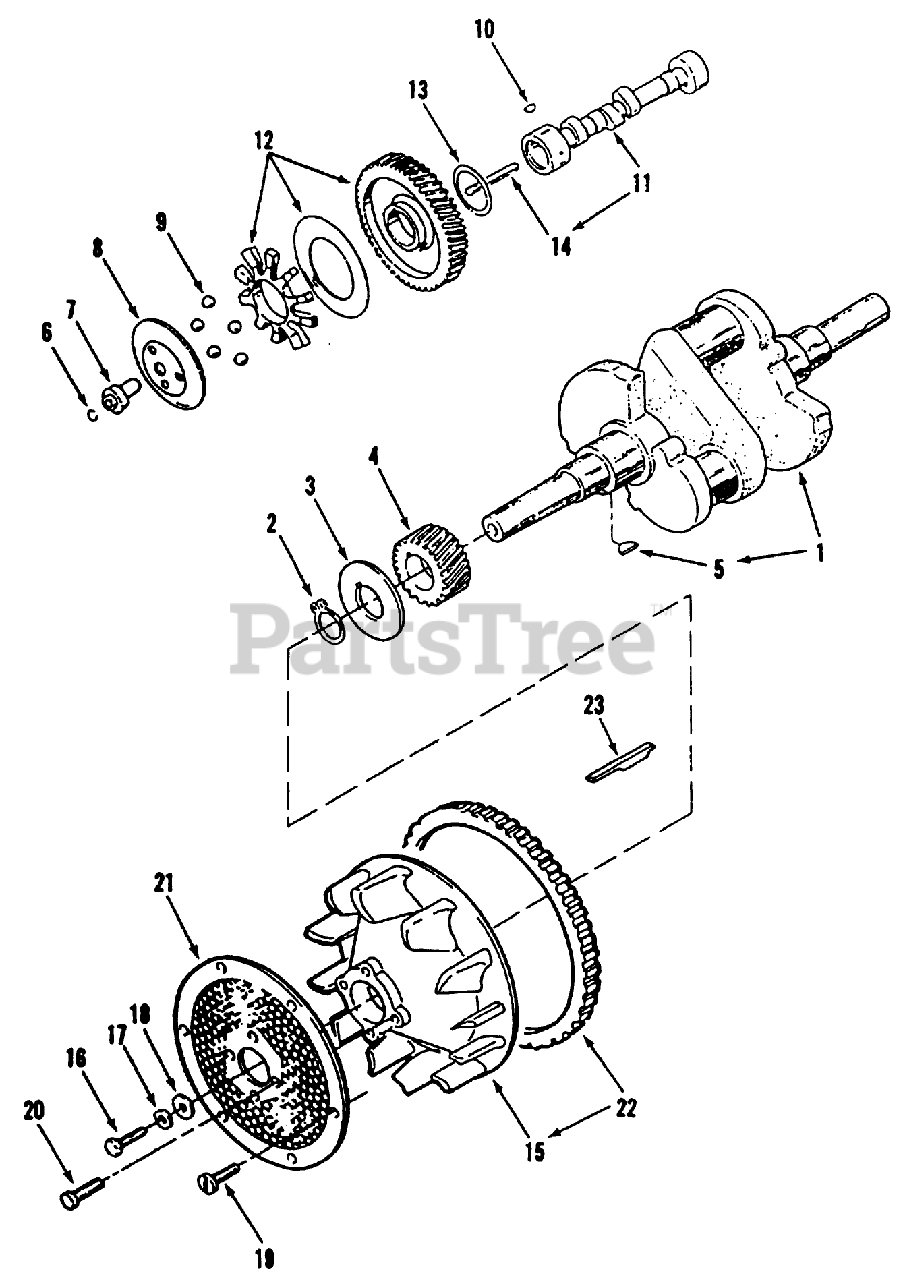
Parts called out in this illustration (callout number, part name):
9	BEARING
17	WASHER-FLAT
21	SCREEN-AIR INLET
23	KEY - MACHINE
